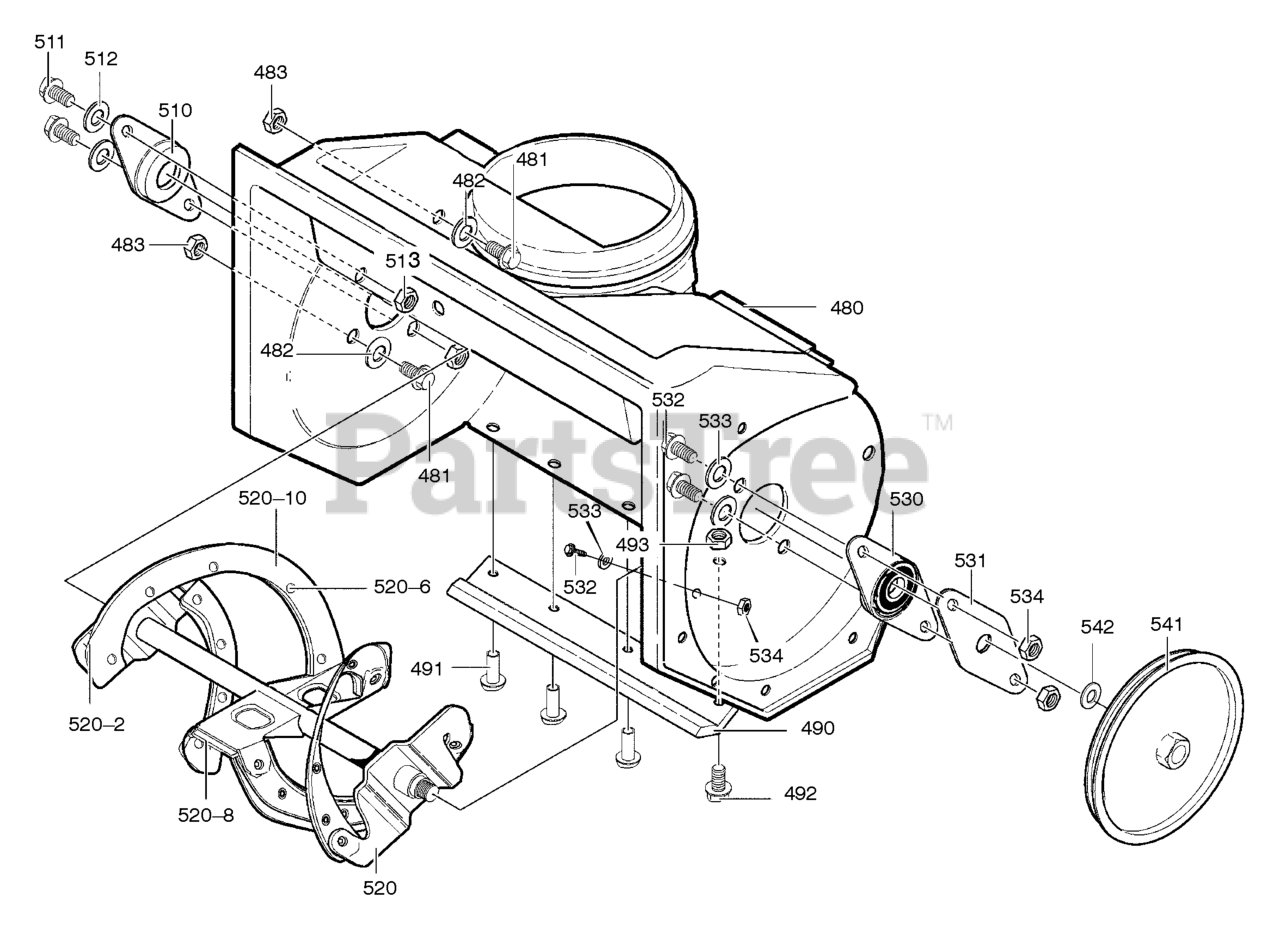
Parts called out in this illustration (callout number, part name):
480	HOUSING, ASSY
481	SCREW, 1/4-20X.75
482	WASHER, FLAT .281X.63X.065
483	NUT, HEX 1/4-20 YZ
490	BLADE, SCRAPER
491	RIVET, OVSET
492	SCREW, 1/4-20X.75
493	NUT, 1/4-20 YZ
510	BEARING, FLANGE
511	SCREW, 1/4-20X1.00
512	WASHER, FLAT .281X.63X.065
513	NUT, 1/4-20
520	AUGER, ASSY
520-2	BLADE, AUGER
520-6	RIVET
520-8	BLADE, CENTER
520-10	AUGER & BLADE SUPPORT
530	BEARING & PLATE ASSY
531	PLATE, RETAINER
532	SCREW, 1/4-20X.63
533	WASHER, FLAT .281X.63X.065
534	NUT, 1/4-20
